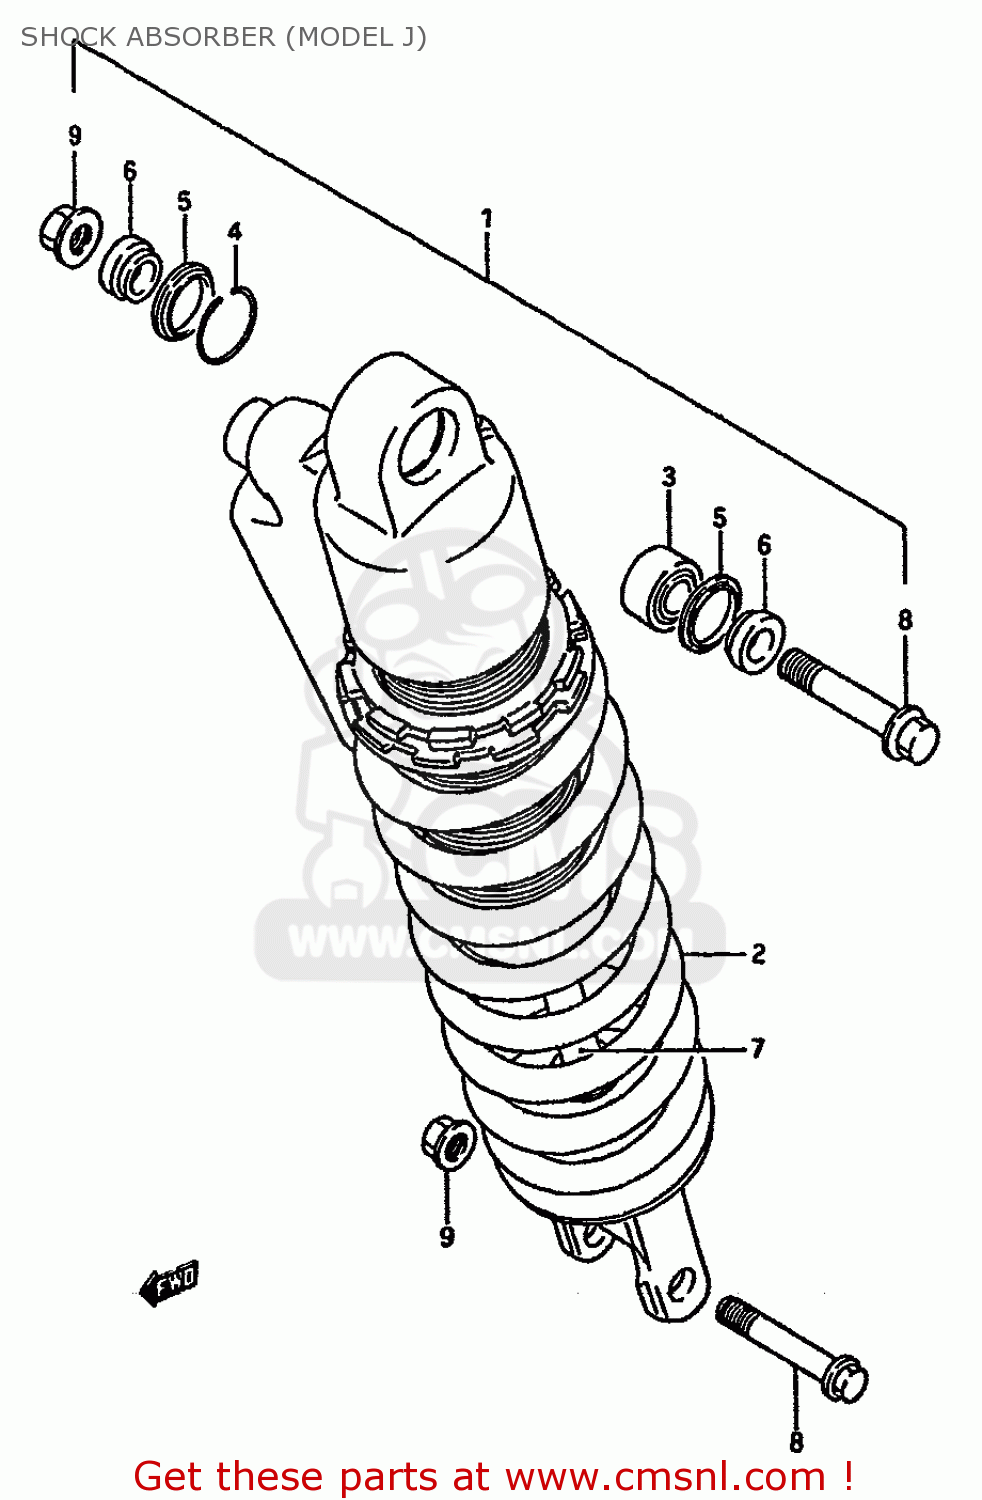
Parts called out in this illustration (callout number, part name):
1	ABSORBER ASSEMBLY,REAR SHOCK
2	SPRING
3	BEARING,RR CUSHION LEVER
4	RING
5	DUST SEAL
6	SPACER
7	ROD,PISTON
8	BOLT,REAR SHOCK ABSORBER
9	NUT
10	SPRING
